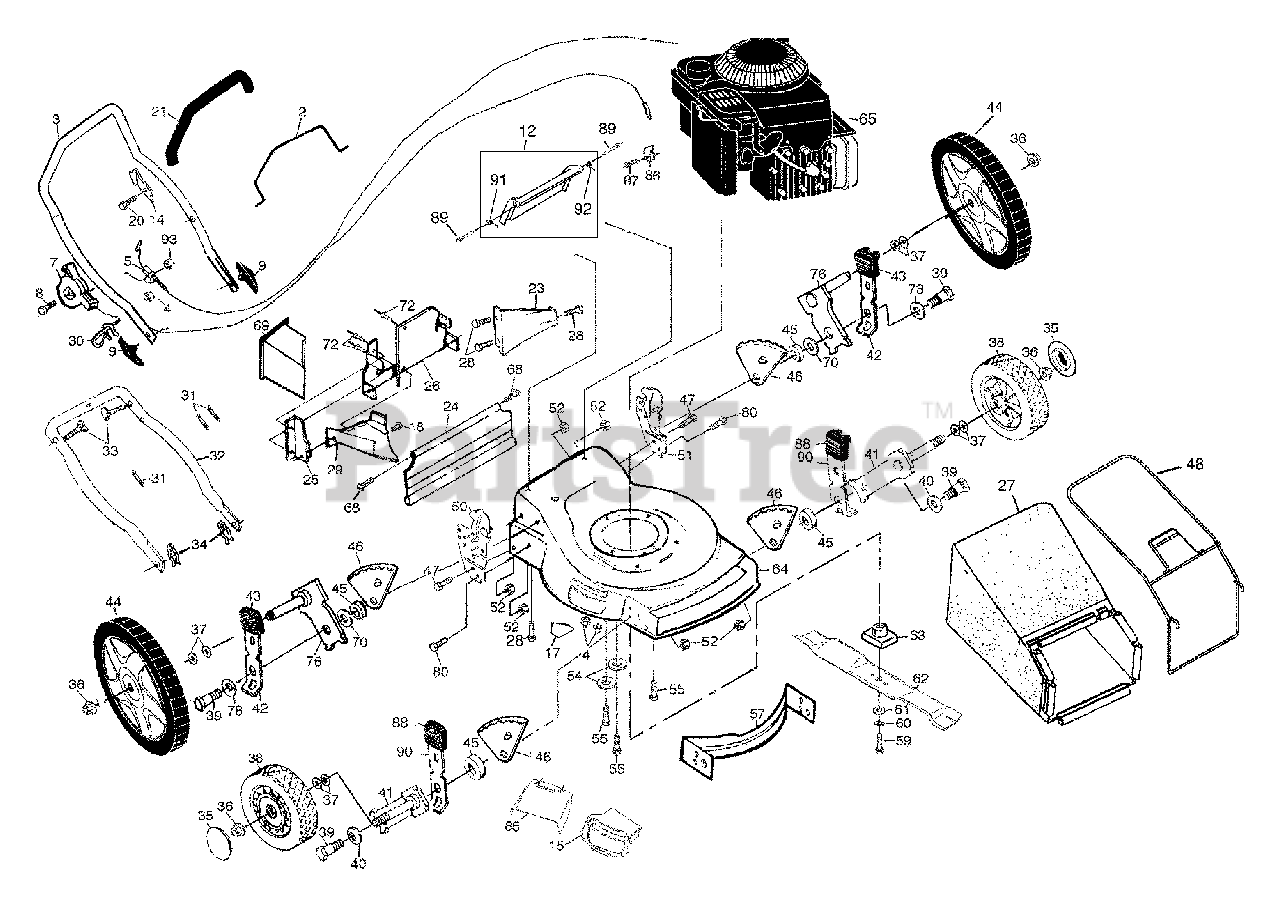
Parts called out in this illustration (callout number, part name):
2	Control Bar
3	Upper Handle
4	Locknut
5	Engine Zone Control Cable
7	Throttle Control
8	Hex Washer Head Screw 1/4-20 x 2-1/8
9	Handle Knob
12	Rear Door Kit
14	Upstop Bracket
15	Combi-Cut Mulcher
17	Danger Decal
20	Hex Washer Head Screw #10-24
21	Handle Grip
23	Rear Baffle
24	Rear Skirt
25	Side Baffle
26	Back Plate
27	Grass Bag
28	Screw Hex Head 1/4-20 x 1/2
29	Discharge Baffle
30	Rope Guide
31	Wire Ties
32	Lower Handle
33	Handle Bolt
34	Hairpin Cotter
36	Flanged Locknut
37	Wave Washer
38	Wheel & Tire Assembly (Front)
39	Shoulder Bolt
40	Belleville Washer
41	Axle Arm
42	Selector Spring
43	Selector Knob
44	Wheel & Tire Assembly (Rear)
45	Spacer
46	Wheel Adjusting Bracket R.R.
47	Self-tapping Screw 5/16-18 x 3/4
48	Catcher Frame
50	Handle Bracket (Right)
51	Handle Bracket (Left)
52	Locknut 3/8-16
55	Hex Head Thread Rolling Screw 3/8-16 x 1
57	Front Baffle
59	Hex Head Machine Screw 3/8-24 x 1-3/8 Gr. 8
60	Helical Lock Washer
61	Hardened Washer
63	Blade Adapter
64	Lawn Mower Housing Kit
68	Hinge Screw
69	Mulcher Plug
70	Flat Washer
76	Axle Arm Assembly
78	Spacer
85	Clip on Guard
86	Cable Clamp
88	Selector Knob
89	Door Bolt
90	Selector Spring
91	Door Spring RH
92	Door Spring LH
93	Nut, Hex
